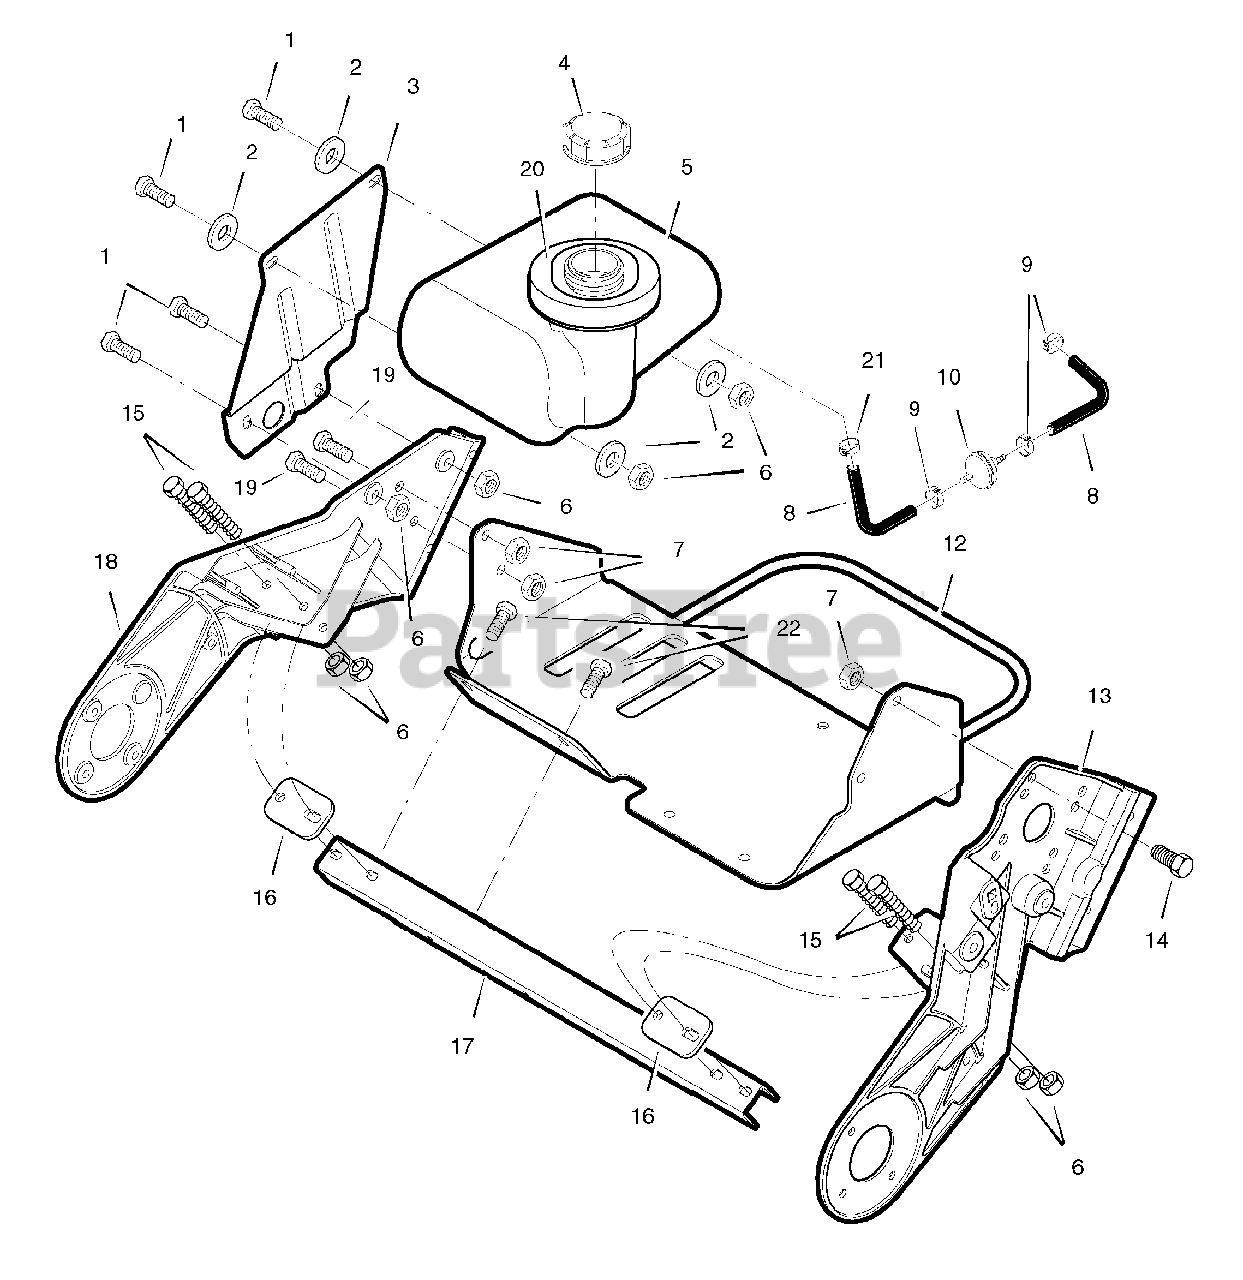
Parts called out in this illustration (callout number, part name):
1	SCREW 1/4-20 x .3/4
2	WASHER FLAT 9/32 x 5/8 x .065
3	BRACKET, Fuel Tank
4	CAP, Fuel Tank
5	TANK, Fuel
6	NUT, Hex 1/4-20
7	NUT, Hex 5/16-18
8	HOSE, FUEL 12 INCHES
9	CLAMP, Fuel Line
10	FILTER, Fuel Line
12	CRADLE ASSEMBLY, Engine
13	FRAME, L.H.
14	SCREW, 5/16-18 x 1/16
15	SCREW, 1/4-20 x 2.00
16	PLATE, Mounting Support
17	SUPPORT, Frame
18	FRAME, R.H.
19	SCREW, 5/16-18 x 3/4
20	RING, Foam
21	CLAMP, Fuel Line, Screw Type
22	SCREW, 1/4-20 x 5/8
